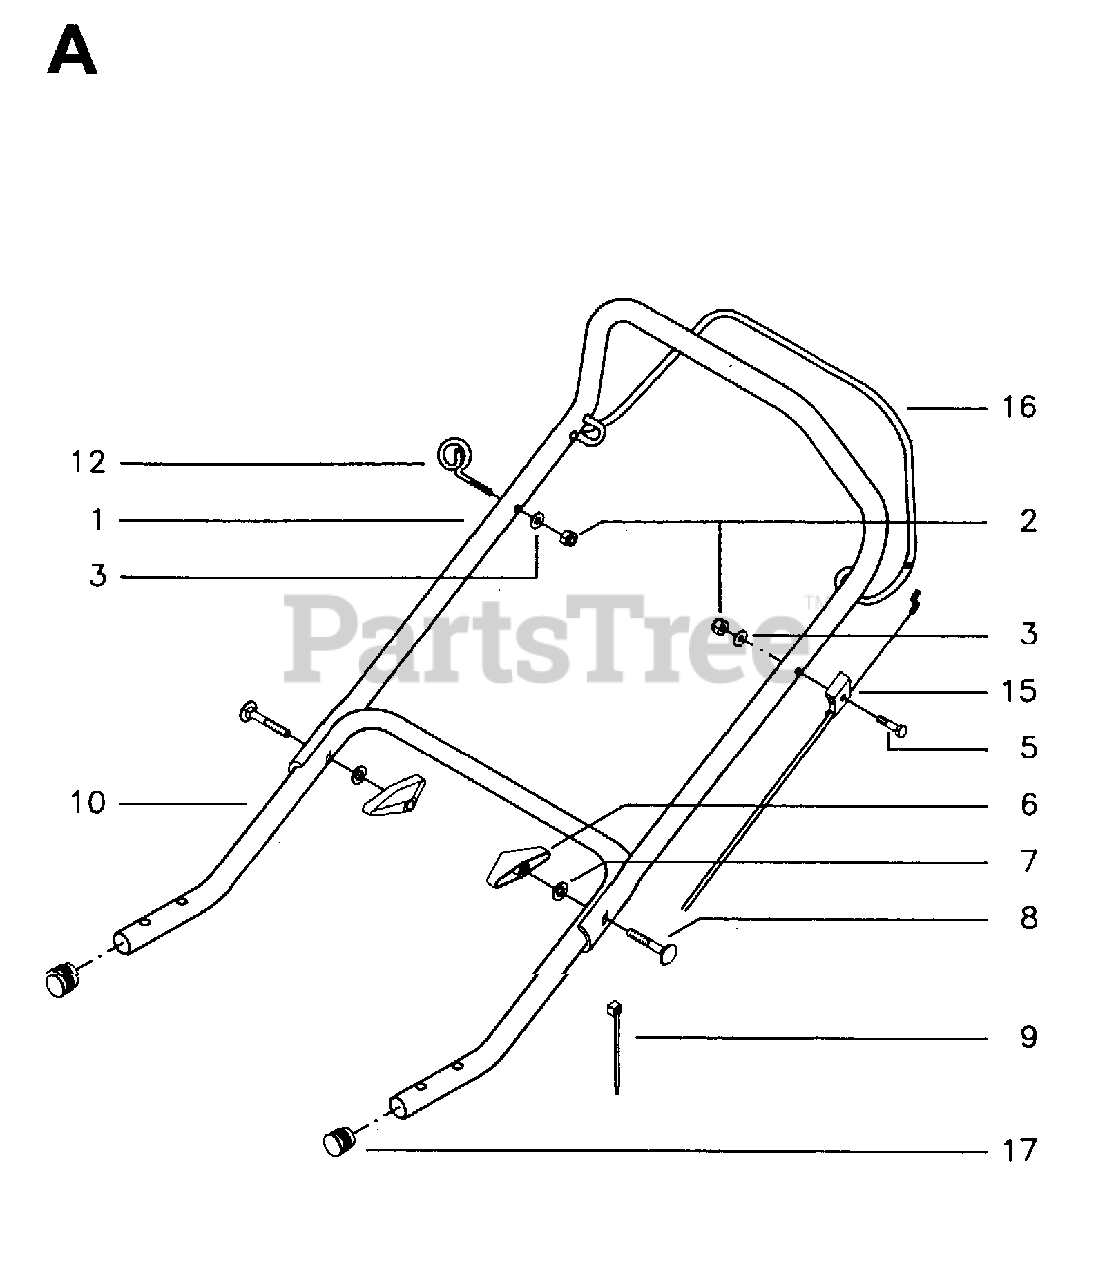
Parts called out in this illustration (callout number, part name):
2	LOCKNUT M6
5	BOLT FLANGE
12	CABLE GUIDE
